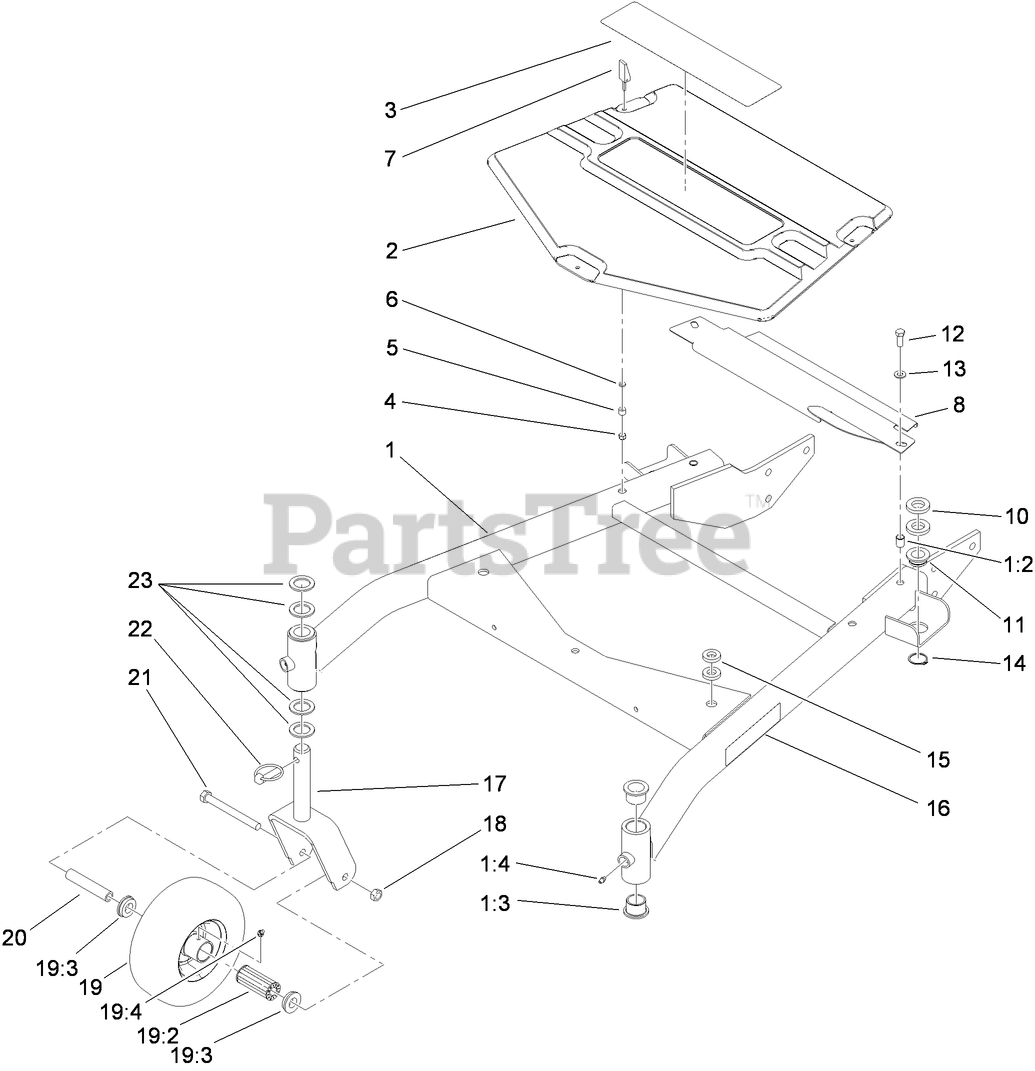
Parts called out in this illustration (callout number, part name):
1	CARRIER FRAME ASM
1:2	INSERT-NUT
1:3	BUSHING
1:4	FITTING-GREASE
2	COVER-FRAME, CARRIER
4	NUT-LOCK, HH
5	BUSHING-LATCH, SWELL
6	WASHER
7	HANDLE-LATCH, SWELL
8	SHIELD-BELT
10	SPACER-SUPPORT, DECK
11	BUSHING-DECK
12	SCREW-HH
13	WASHER-FLAT
14	RING-RETAINING
15	SPACER
16	DECAL-HOC
17	FORK-CASTOR
18	NUT-HEX
19	WHEEL AND TIRE ASM
19:2	BEARING-ROLLER
19:3	BUSHING
19:4	FITTING-GREASE
20	BUSHING-SPANNER
21	SCREW-HH
22	PIN-LYNCH
23	WASHER-THRUST
